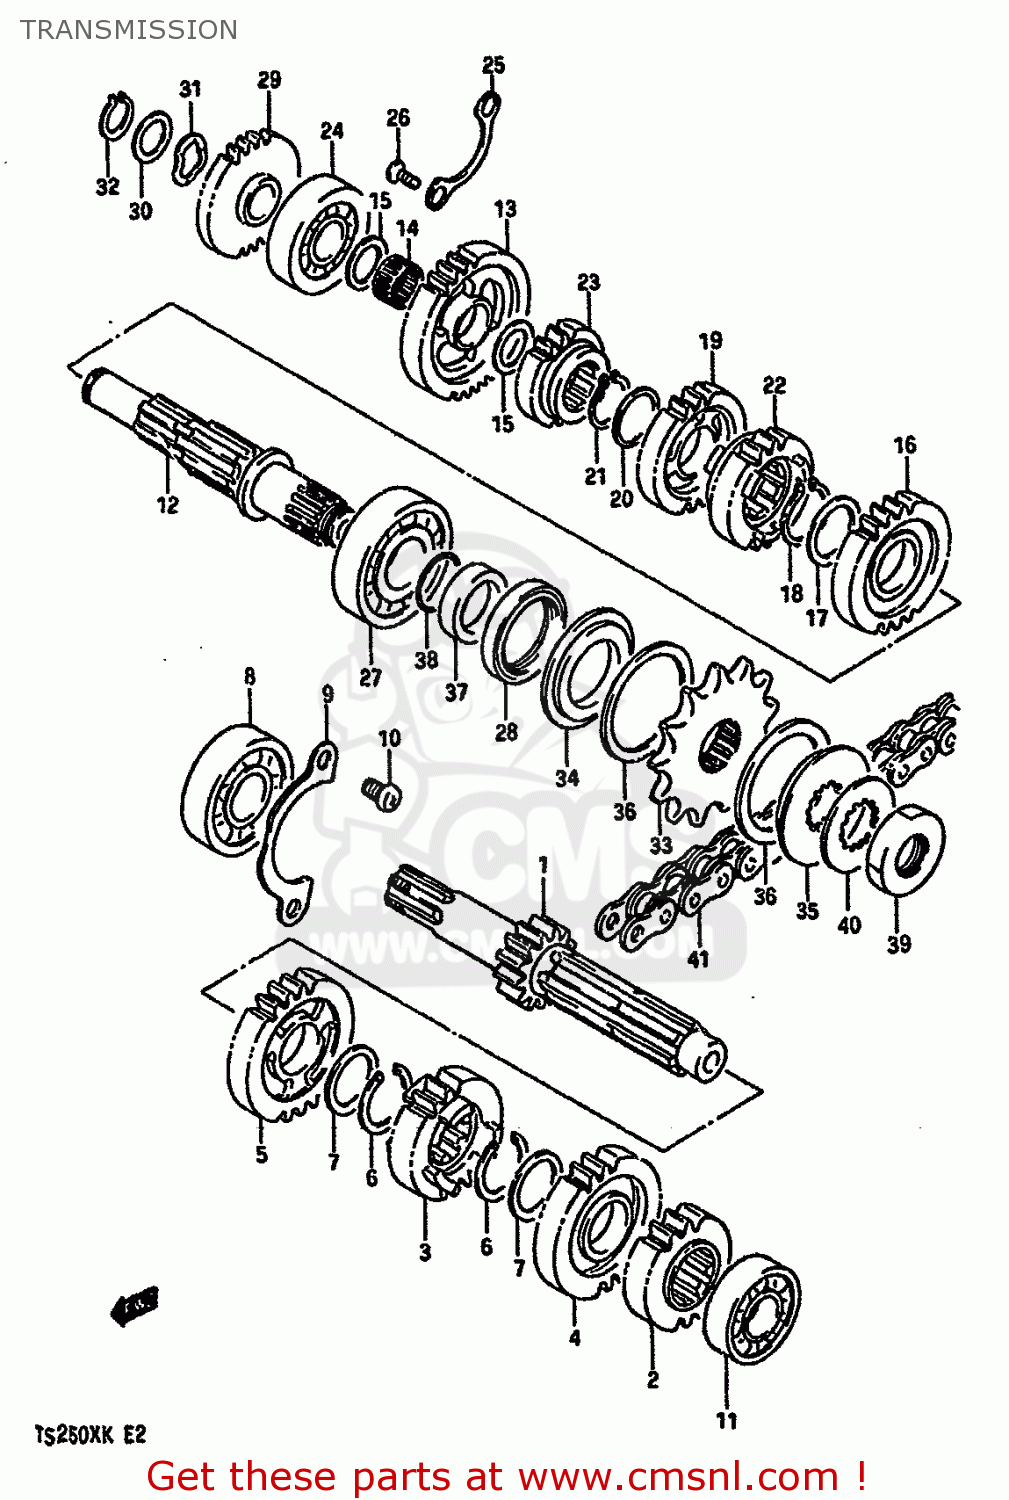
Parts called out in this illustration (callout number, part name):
1	COUNTERSHAFT (NT:13)
2	GEAR,2ND DRIVE
3	GEAR,3RD DRIVE (NT:19)
4	GEAR,4TH DRIVE (NT:22)
5	GEAR,5TH DRIVE (NT:24)
6	CIRCLIP
7	SHIM
8	BEARING(20X52X15)
9	RETAINER,CENTER SHAFT BEARING
10	SCREW 6X12
11	BEARING(17X40X12)
12	DRIVESHAFT
13	GEAR,1ST DRIVEN (NT:31)
14	BEARING(17X21X9.8)
15	WASHER (17X26X1)
16	GEAR,2ND DRIVEN (NT:24)
17	SHIM
18	RING,SNAP
19	GEAR,3RD DRIVEN(NT:21)
20	SHIM
21	CIRCLIP
22	GEAR,4TH DRIVEN(NT:19)
23	GEAR,5TH DRIVEN(NT:17)
24	BEARING(17X40X12)
25	PLATE,DRIVESHAFT BEARING
26	SCREW
27	BEARING
28	SEAL,OIL(32X42X6)
29	GEAR,KICK STARTER IDLE
30	SHIM
31	WASHER
32	CIRCLIP
33	SPROCKET,ENGINE (NT:13)
34	HOLDER,ENGINE SPROCKET
35	HOLDER,ENGINE SPROCKET
36	DAMPER
37	SPACER(22X32X9.5)
38	O RING(D:1.7,ID:22)
39	NUT
40	WASHER,LOCK
41	CHAIN ASSEMBLY,DRIVE RK520
